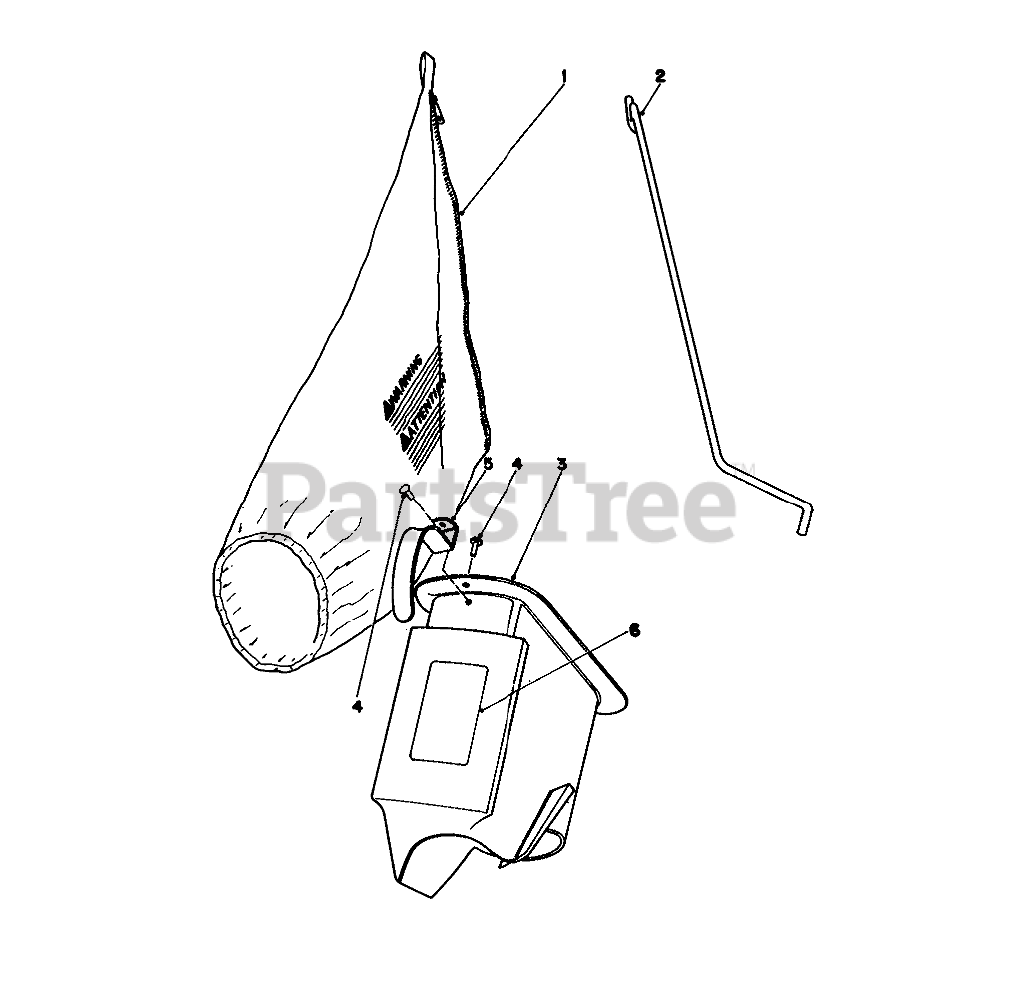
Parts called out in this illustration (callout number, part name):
1	BAG REPLACMNT44-0540
2	Bag Rod
3	Grass Chute (Incl. Ref.#4&5)
4	RIVET 3/16 X 7/16
5	HANDLE-GRASS CHUTE
6	THROTTLE LEVER
